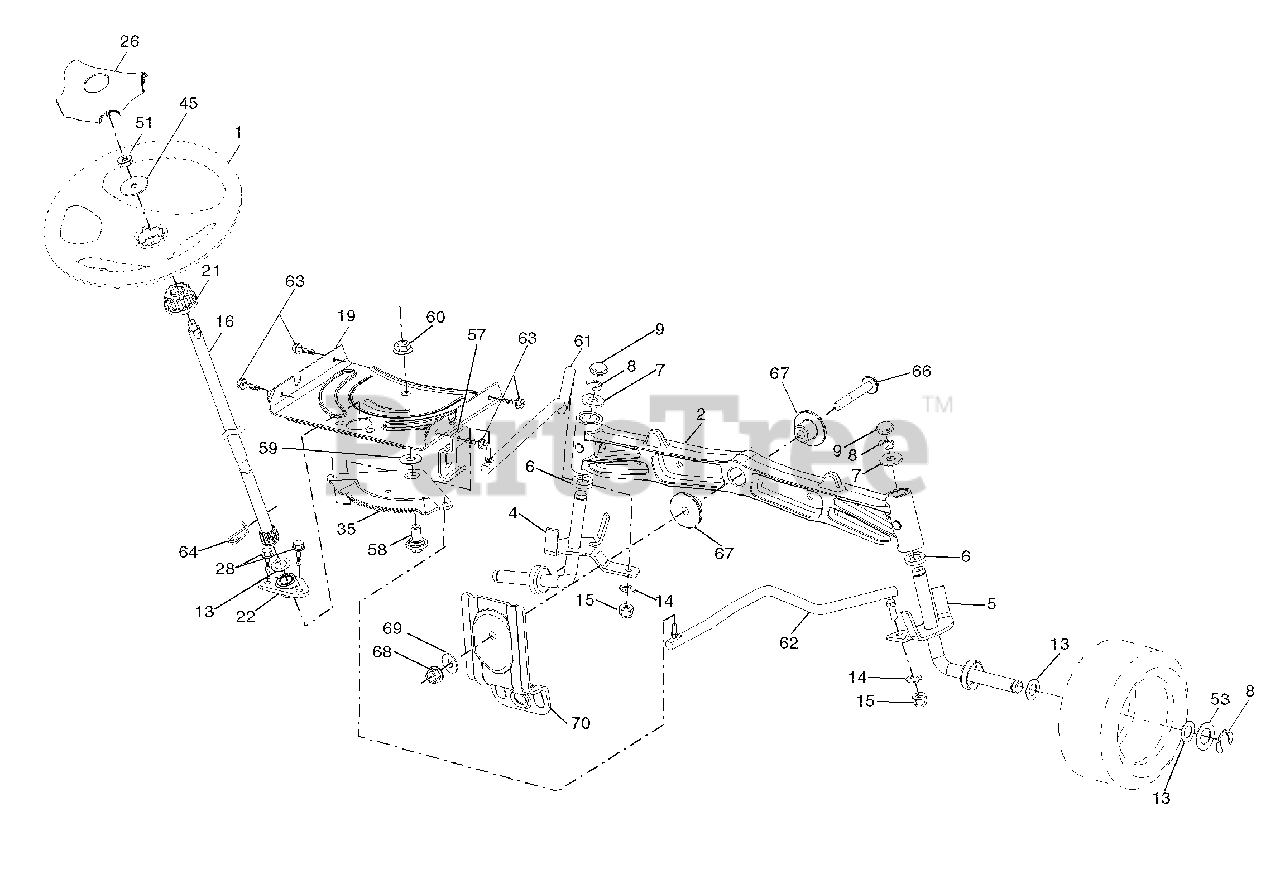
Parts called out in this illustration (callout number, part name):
1	Wheel, Steering
2	Axle Asm., Front
4	Spindle Asm., LH
5	Spindle Asm., RH
6	Bearing, Race Thrust Harden
7	Washer 25/32 x 1-5/8 x 16 Ga.
8	Ring, Clip #T5304-75
9	Cap, Spindle
13	Washer 25/32 x 1-1/4 x 16 Ga.
14	Washer, Lock Hvy Hlcl Spr 3/8
15	Nut, Crown Lock 3/8-24 unf
16	Shaft Steering
19	Plate Steering
21	Adapter, Wheel Steering
22	Bushing, Strg. Blk
26	Insert, Wheel Steering
28	Screw 3/8-16 x 3/4
35	Gear, Sector Plate
45	Washer 9/16 x 2-3/8 x 12 Ga.
51	Nut Hex Jam Toplock 1/2-20 unf
53	Washer Hardened .793 x 1.637 x .060
57	Bracket Upstop
58	Bolt Shoulder Sector Pivot CFM
59	Washer Thrust Sector Steering
60	Nut Flange Lock 5/8-11
61	Draglink, LH
62	Draglink, RH
63	Screw 5/16-18 x 3/4
64	Retainer Clip Spring Steering
66	Bolt Hex Fghd 7/16-14 x 3 Serr
67	Bushing PM Front Axle
68	Nut Lock Flange 7/16-14 Gr. 5
69	Washer 1.5 x .505 x 118
70	Bracket Deck Susp. Front
